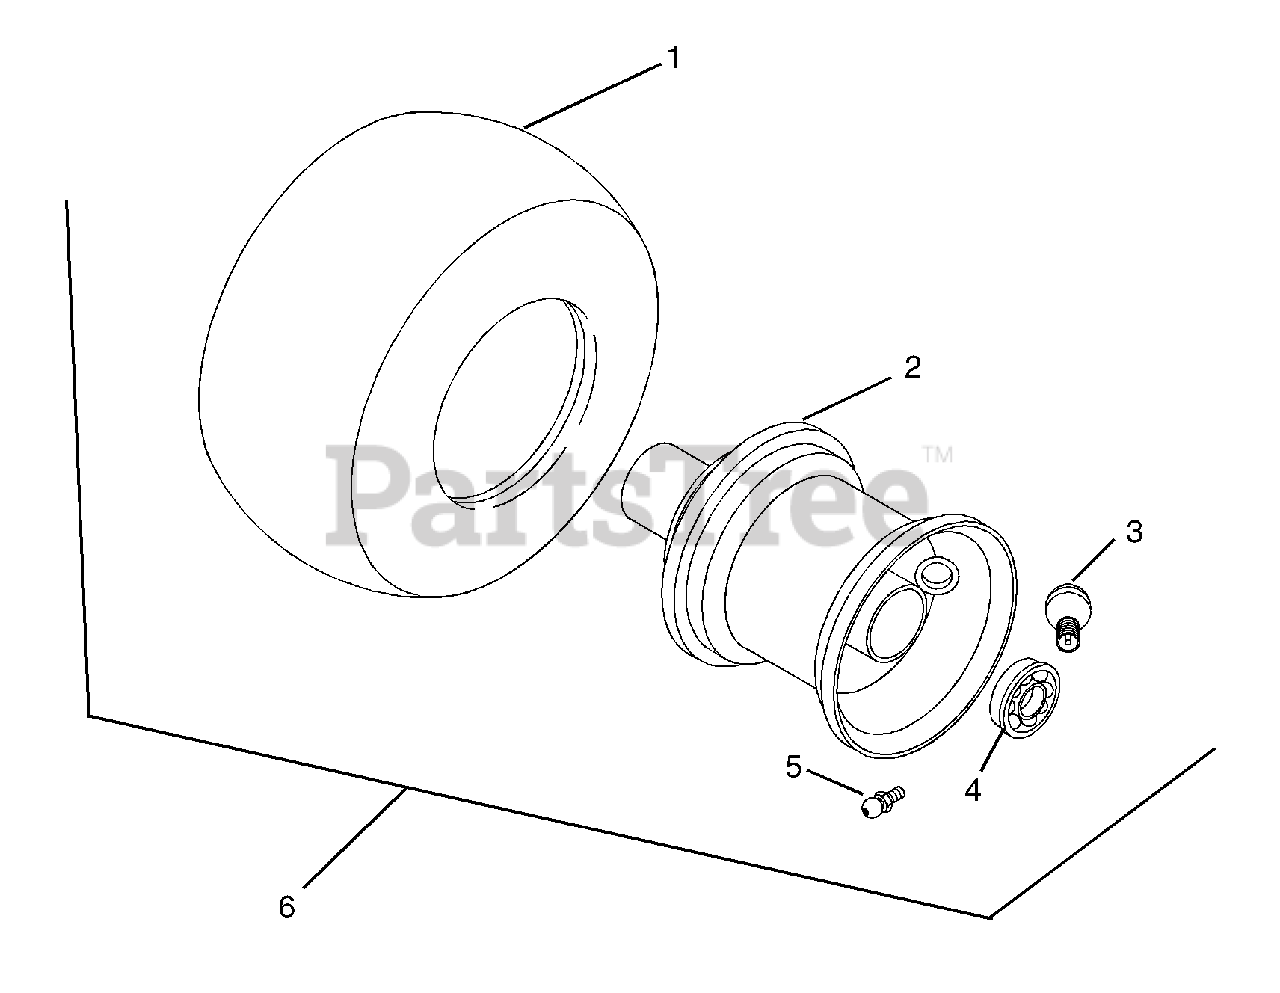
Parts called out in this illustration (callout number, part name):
1	Tire 13 x 6.50-6
2	Rim-Assembly 4.5 x 3.75
3	Valve Stem Assembly
4	Radial Bearing
5	Fitting-Lube .25-28 x .256
6	Assembly, Wheel, 13 x 6.50-6
